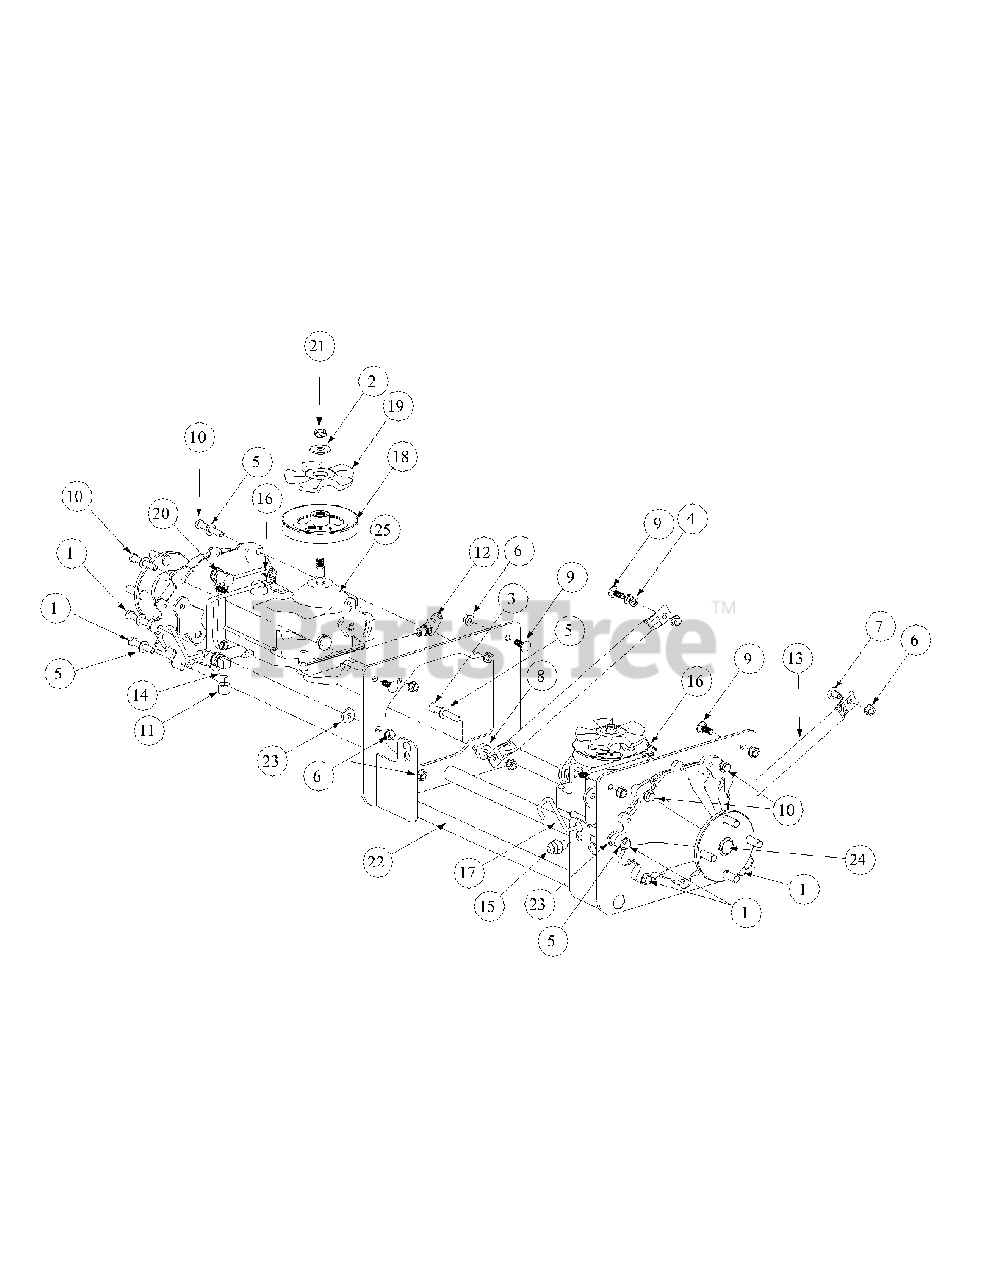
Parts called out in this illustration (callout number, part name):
1	Hex Cap Screw, 3/8-16 x 2
2	Flat Washer, 1/2
3	Hex Cap Screw, 3/8-16 x 2.5
4	Lock Washer, 3/8
5	Flat Washer, 3/8
6	Flange Lock Hex Nut, 3/8-16
7	Carriage Bolt, 3/8-16 x .75 Long
8	Spacer, .406 ID x 1.00 OD x .38
9	Carriage Bolt, 3/8-16 x 1
10	Hex Cap Screw, 3/8-16 x 2.25
11	Nut Cap, 3/8
12	Elbow Fitting, 3/8 - 1/2 x 45°.
14	Elbow Fitting, 3/8 x 3/8
15	Fitting, 1/2 x 3x8
16	Cotter Pin, .072 x 1.12 Long
17	Pump Release Rod
18	Slotted Hydro Pulley
19	Pulley Hydro Fan
20	Elbow Fitting, O-Ring 3/8, 1/2 Flare
21	Insert Lock Jam Nut, 1/2-20
22	Sub-Frame Weldment
23	Flat Washer, .385 x 1.0 OD x .13
24	Right Hand Pump Assembly
25	Left Hand Pump Assembly
